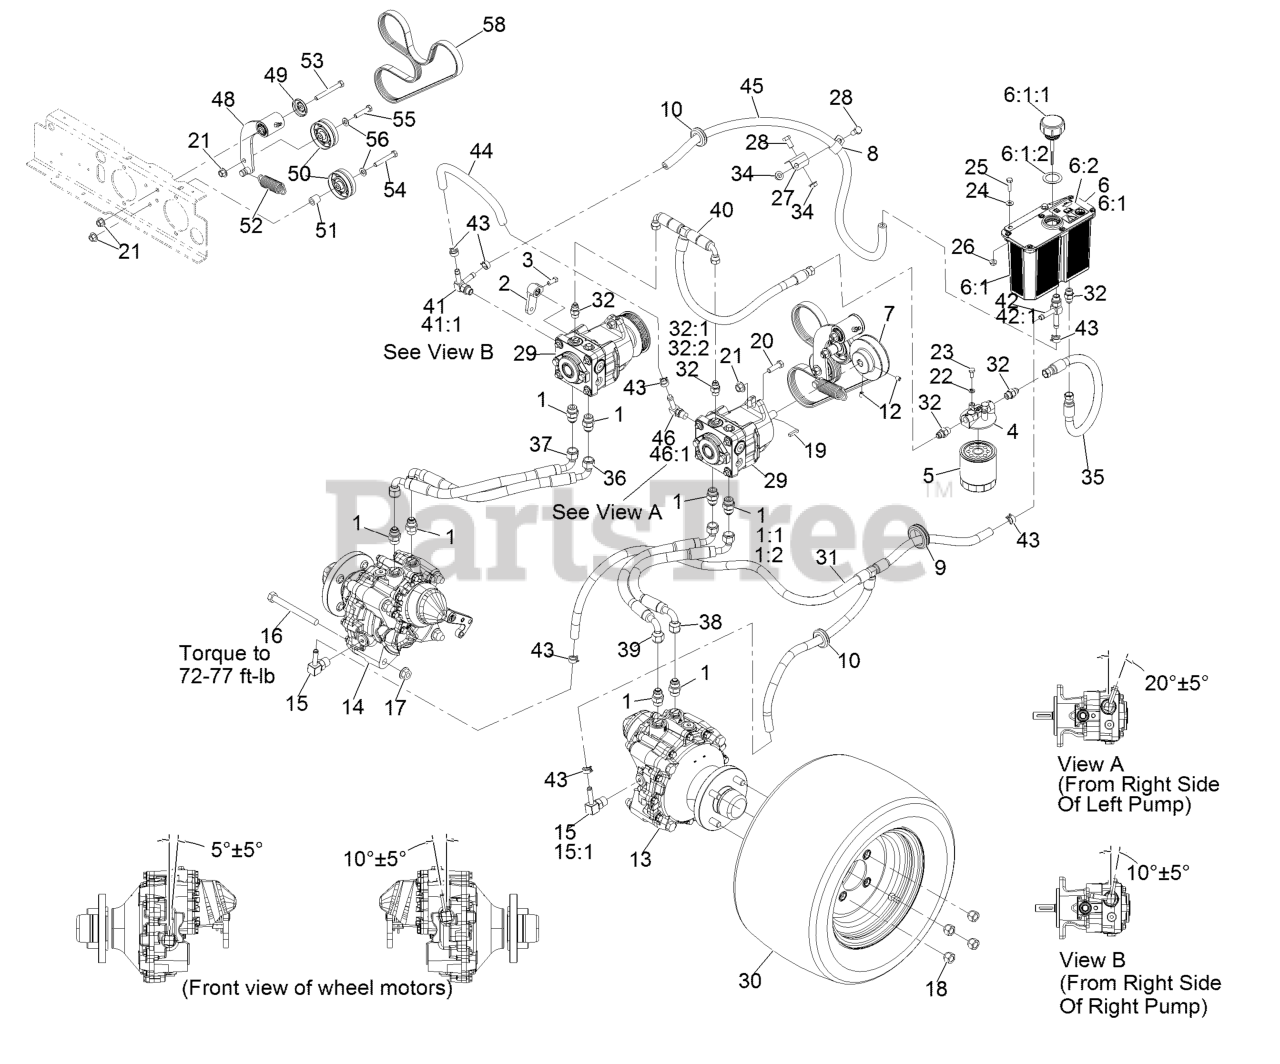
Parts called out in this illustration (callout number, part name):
1	Adapter-Straight
1:1	O-Ring-SAE #8
1:2	O-Ring-37 Flare #8
2	Arm-Control, Pump
3	Screw-Set, SQH 5/16-18 X 3/4
4	Filter-Head
5	Element, Oil Filter
6	Reservoir ASM
6:1	Reservoir-HYD
6:1:1	Reservoir Cap ASM
6:1:2	Gasket-Cap
6:2	Decal-Warning
8	Clip-Loom 5/8
9	Grommet
10	Grommet
12	Setscrew-5/16-18 X 3/8
13	Motor-HYD, LH
14	Motor-HYD, RH
15	Fitting-HYD, 90 DEG
15:1	O-Ring
16	Screw-HH 1/2-13 X 5
17	Nut-Whizlock 1/2-13
18	Nut-Lug 1/2-20
19	Key-5Mm X 5Mm X 25Mm
20	Screw-HH 3/8-16 X 1 1/4
21	Nut-Whizlock 3/8-16
22	Washer-Lock 1/4 Heavy
23	Screw-HH 1/4-20 X 5/8
24	Washer-1/4 SAE
25	Screw-HH 1/4-20 X 1
26	Nut-Whizlock 1/4-20
27	Bracket-Clamp
28	Screw-HH 3/8-16 X 3/4
29	12Cc Hydro Pump ASM
30	Tire And Wheel ASM
31	Hydraulic Hose ASM
32	Adapter-Straight
32:1	O-Ring-SAE #6
32:2	O-Ring-37 Flare #6
34	Nut-Whizlock 3/8-16
35	Hydraulic Hose ASM
36	Hydraulic Hose ASM
37	Hydraulic Hose ASM
38	Hydraulic Hose ASM
39	Hydraulic Hose ASM
40	Hydraulic Hose ASM
41	Adapter-Tee Special
41:1	O-Ring
42	Adapter-Running Tee
42:1	O-Ring
43	Clamp-Hose 11/16
44	Hose-HYD
45	Hose-HYD
46	Fitting-Elbow, 90
46:1	O-Ring
48	Short Idler ASM
49	Guard-Top
51	Spacer-Mounting, Steering
53	Screw-HH 3/8-16 X 3-1/4
54	Screw-HH 3/8-16 X 2 1/2
55	Screw-HH 3/8-16 X 1 3/4
56	Washer-3/8 SAE
58	Belt
